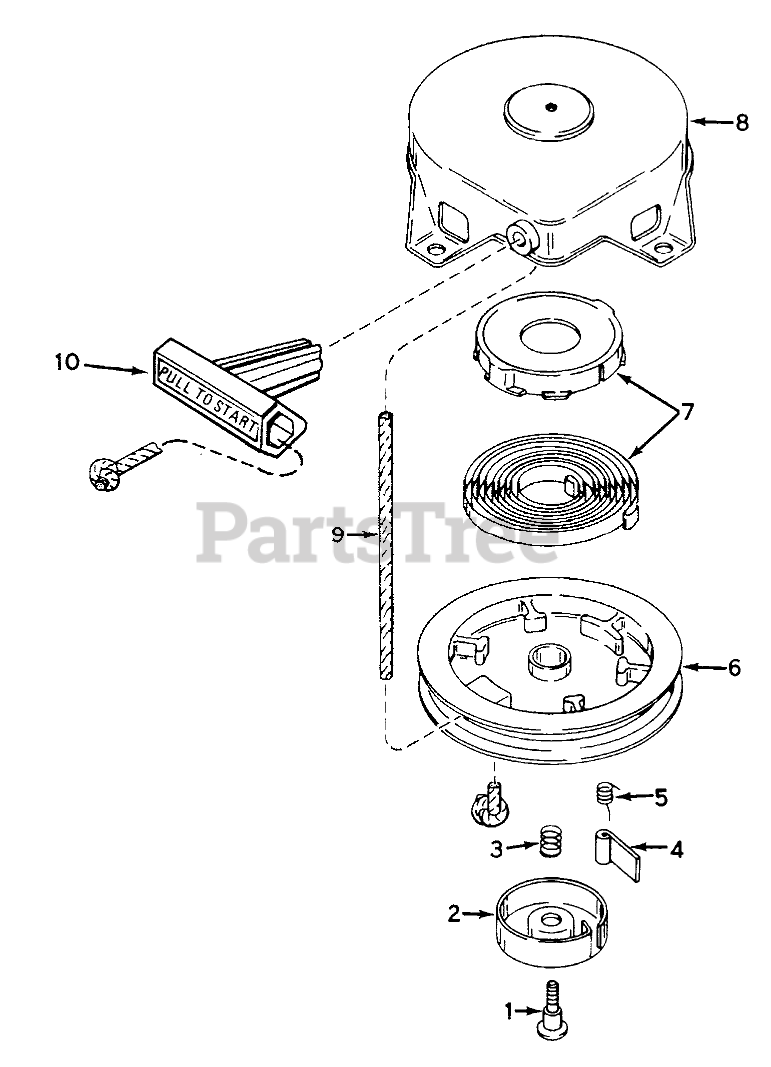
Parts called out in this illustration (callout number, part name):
2	Retainer
3	Spring-Brake
4	Dog-Starter
5	Spring-Dog
7	Spring & Keeper Assy
8	Housing-Starter
9	Rope-Starter
10	Handle-Starter
